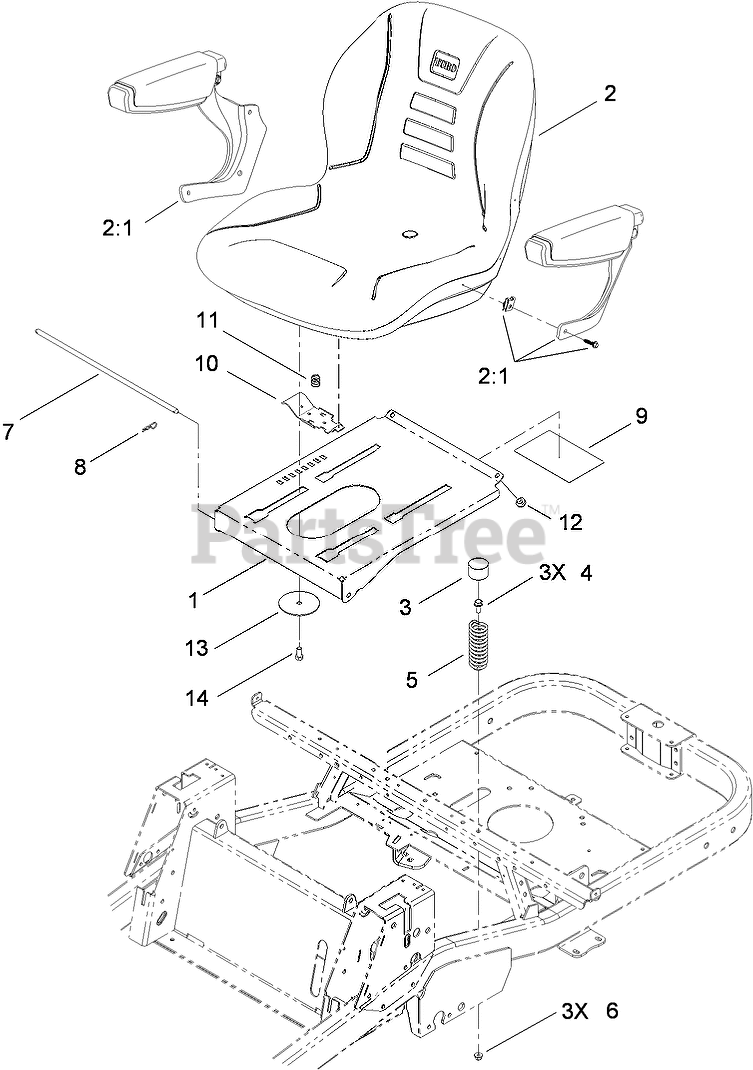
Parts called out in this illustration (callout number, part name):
1	PAN-SEAT
2	18 INCH SEAT ASM
2:1	ARMREST KIT
3	CAP-PROTECTOR
4	SCREW-HHF
5	SPRING-COMPRESSION
6	NUT-HF, NI
7	ROD-STOP
8	PIN-COTTER
9	DECAL-MAINTENANCE
10	LATCH-SEAT
11	SPRING-COMPRESSION
12	BUMPER
13	WASHER-SEAT
14	SCREW-HH
